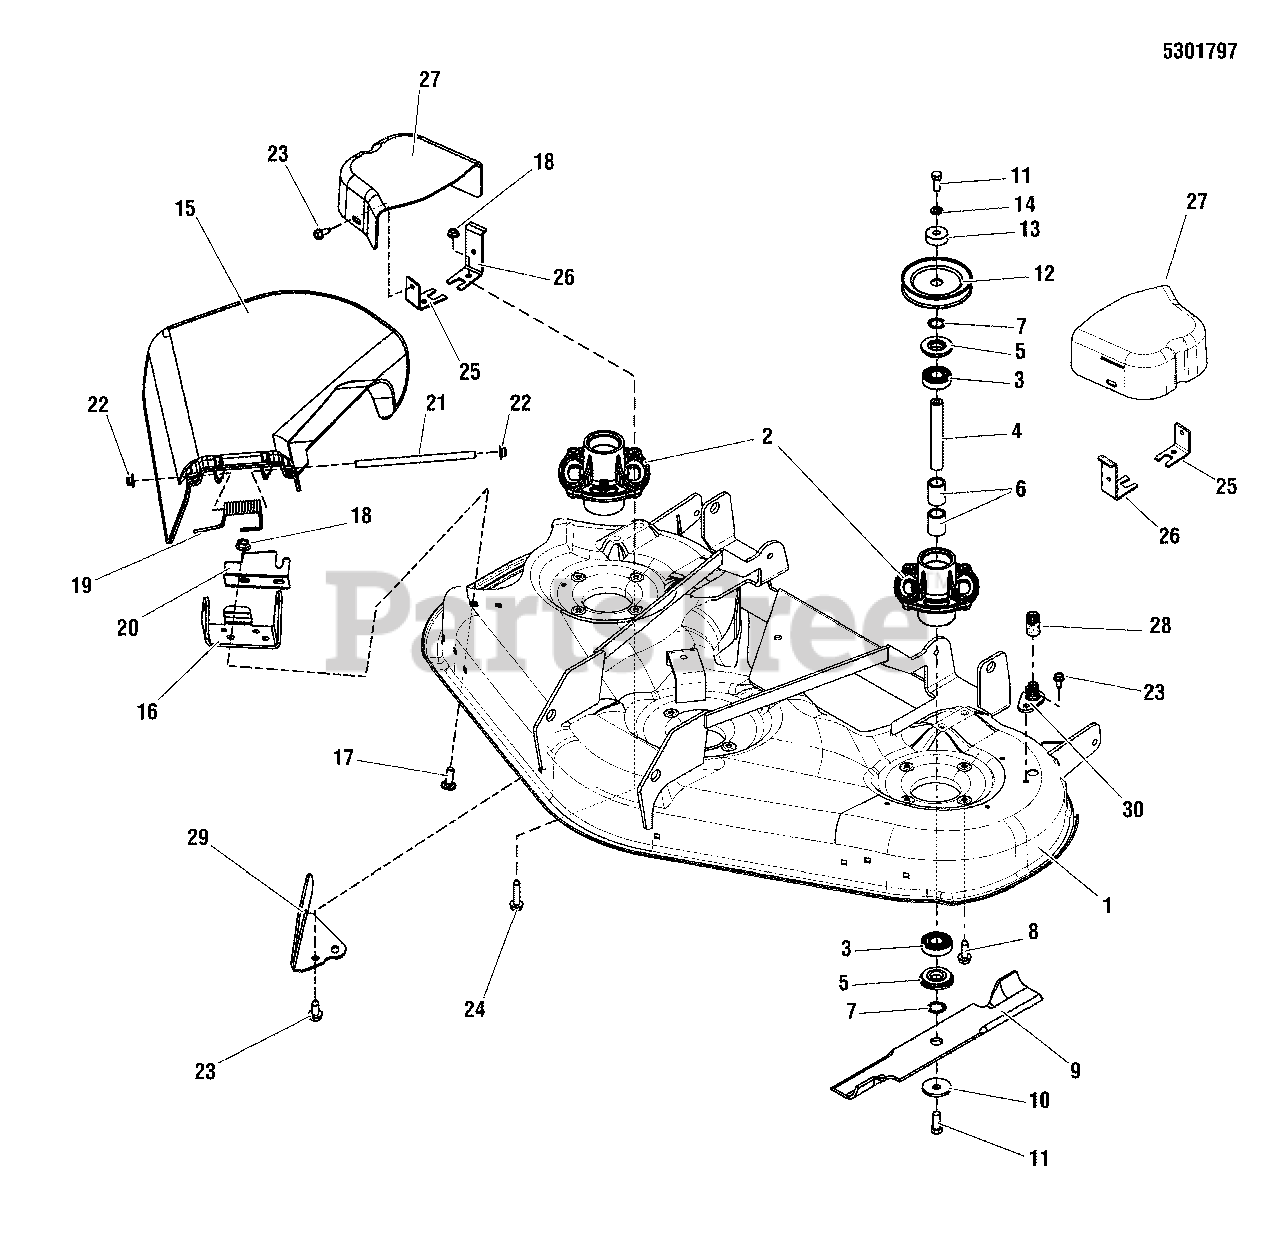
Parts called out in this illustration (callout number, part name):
1	DECK SHELL W/ DECALS, 46, SMI ZT3000
2	HOUSING, SPINDLE, CAST STEEL, MACHINED
3	BEARING-BALL 20MM 46" MWR
4	SHAFT-SPINDLE 20MM DIA 134.60MM LG
5	SHIELD-ARBOR 2.050OD 46" MWR
6	SPACER-BEARING PWDR MTL 46" MWR
7	RING-SELF LOCKING 46" MWR
8	SCREW-HEX WSHR HD TAPTT5/16-18X1.000BLK
9	BLADE-MOWER 16.13LG 46" MWR
10	WASHER, SPRING 0.475IDX1.75ODX.156TH BLK
11	CAPSCREW-HEX HD 7/16-14X1.000 G5 BLK
12	PULLEY-4.6 OD 11GA SPLIT 46" MWR
13	SPACER-LOWER DRIVE 46" MWR
14	LOCKWSHER-SPRING .438 BLK
15	DEFLECTOR-DISCH PLASTIC 46/52 DECKS
16	PIVOT, HINGE
17	BOLT-RD HD SH SQ NK 5/16-18X0.750 G5 BLK
18	NUT-HEX FLANGE 5/16-18, WHIZ LK SM, YZ
19	SPRING-TORS DEFLECTOR 2.16LG 46" MWR
20	PLATE, DEFLECTOR CLOSEOFF
21	ROD, DEFLECTOR, YELLOW ZINC
22	NUT, PUSH, 5/16 BZ
23	SCREW-HEX WSHR HD TAPTT5/16-18X0.750BLK
24	SCREW-HEX WSHR HD TAPTT5/16-18X1.500 BLK
25	BRKT, BELT COVER, SHORT
26	BRKT, BELT COVER, LONG W/ TAB
27	COVER-BELT BLACK POLY 46 + 52" MWRS
28	WASHOUT PORT-CONNECTOR 46+52" BLK POLY
29	BAFFLE, PINCHOFF
30	ADAPTER-WASHOUT PORT 46+52" PLASTIC
